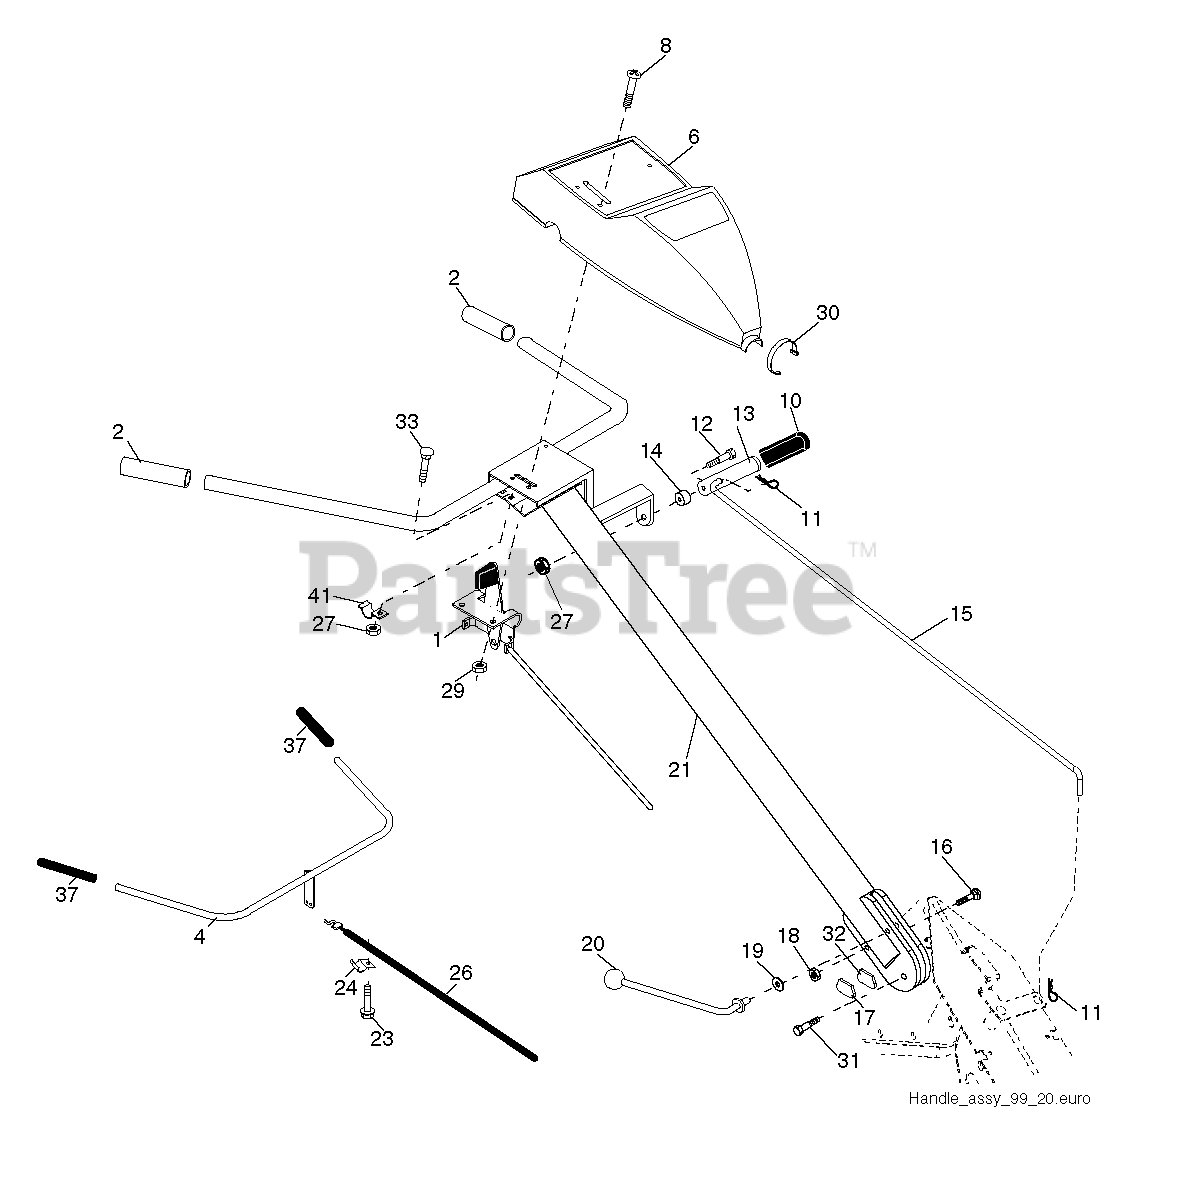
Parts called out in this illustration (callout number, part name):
1	THROTTLE.CONTROL.
2	GRIP.1X5.06
4	CONTROL BAR ASSY
6	RP CONTROL PANEL
8	SCREW.PNHD.10-24
10	GRIP T
11	RETAINER M
12	SHOULDER BOLT ST
13	HANDLE.SHIFT.TILLER
14	GROMMET.RUBBER.CRT.TILLER
15	ROD.SHIFT.YARD PRO.UNIVERSAL.
16	BOLT D
17	LOCK.HANDLE.CRT
19	WASHER CRT
20	LEVER.LOCK.CRT
21	HANDLE.ASM.TILLER.GREY.
23	TAPPING SCREW
24	CONDUIT.CLIP.PLATED
26	CABLE.CLUTCH
27	NUT T
29	NUT **
30	TIE CABLE CRT
31	BOLT.PIVOT
32	LOCK HANDLE
37	GRIP BAR CRT(1)
41	CLAMP.BAR.CRT.BLACK
